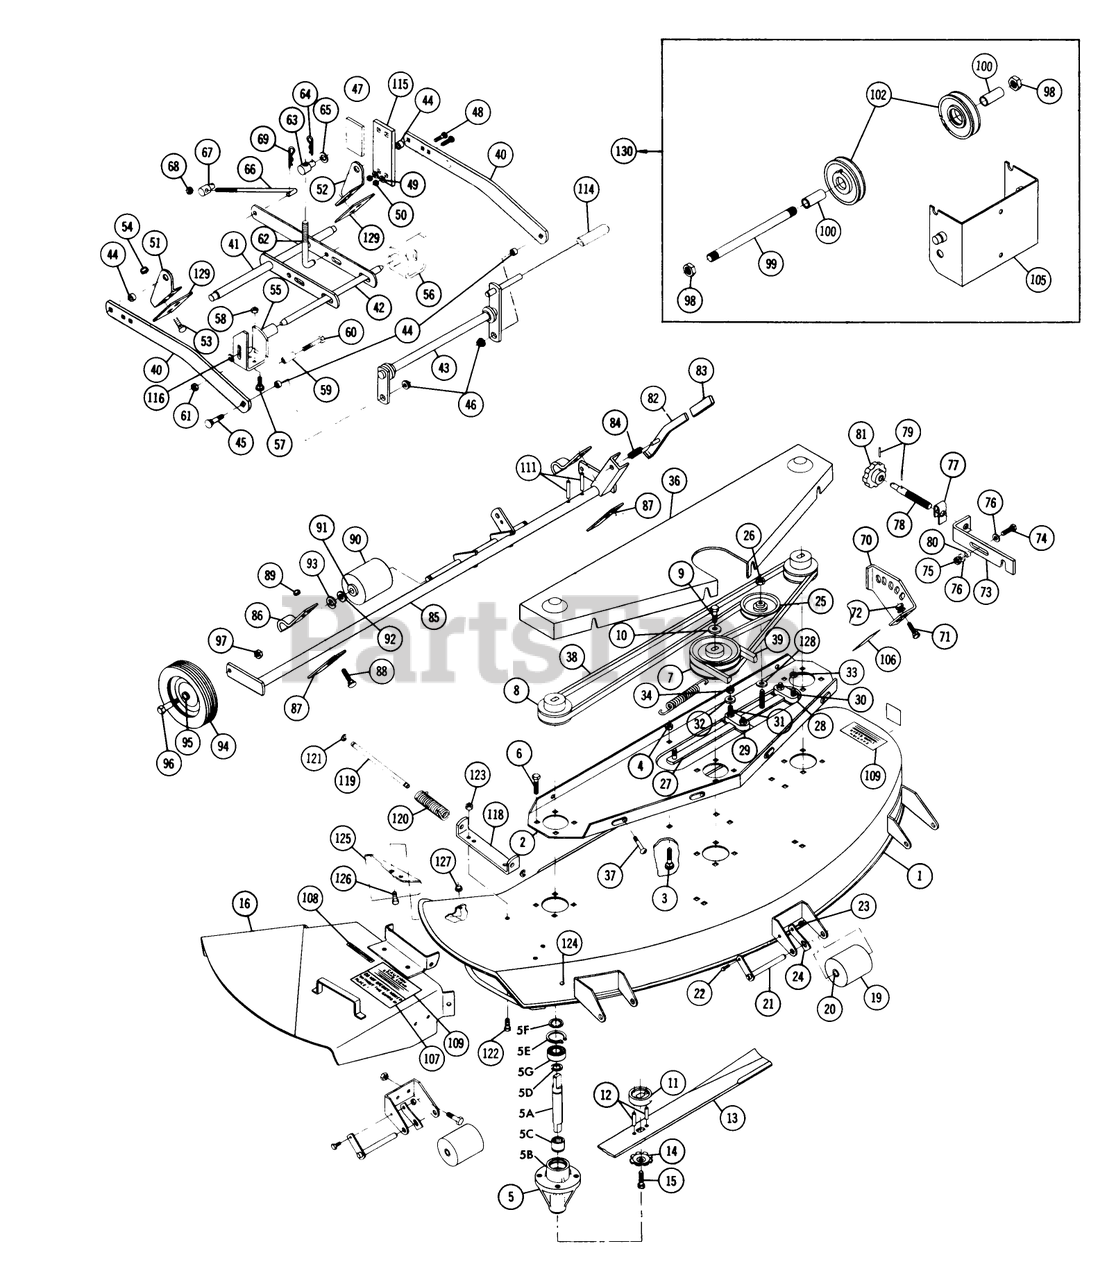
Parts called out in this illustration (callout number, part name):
1	Deck
2	Support
3	Bolt-Carriage
4	NUT
5	Spindle Assy.
5A	SHAFT SPINDLE
5B	HOUSING SPINDLE
5C	NEEDLE BEARING
5D	Snap Ring
5E	INT SNAP RING
5F	BUSHING
5G	BEARING
6	Bolt
7	Pulley-Center
8	Pulley-Right & Left
9	Bolt
10	WASHER
11	Cup-Spindle
12	SPIROL ROLL PIN
13	BLADE KIT 48 LF
14	WASHER
15	Bolt
16	Chute Extension
19	Roller
20	BUSHING
21	Roller Shaft
22	H H C S
23	Nut
24	SPRING ROLLER STOP
25	Pulley-Idler
26	Nut
27	ASSY BAR IDLER SUPPO
28	Side Block
29	SLIDE
30	Bolt-Carriage
31	Bolt-Carriage
32	WASHER 5/16 SAE
33	Nut
34	Nut
35	SPRING R
36	Cover
37	Screw
38	V-BELT
39	V BELT
40	Bar Draft
41	Leveler Ass-y.
42	SHAFT-FRONT R
43	Hitch Assy.
44	SPACER
45	Bolt
46	LOCKNUT-FLANGE
47	BUMPER
48	Bolt-Carriage
49	Collar
50	Nut
51	Bracket-R.H.
52	Bracket-L.H.
53	Bolt-Carriage
54	Nut
55	Bracket-RH Front
56	LH FT DECK BRKT A R
57	Bolt-Carriage
58	Nut
59	SPACER-BEARING
60	7/16-14X13/4 HEX BLT
61	Nut
62	LIFT ROD
63	ROD-TRUNNION LIFT
64	Hairpin
65	Washer
66	ROD-LEVELER
67	TRUNNION-LIFT
68	NUT
69	Hairpin Cotter
70	LH QUADRANT R
71	Bolt
72	NUT
73	Hitch Adjustment Link
74	Bolt
75	Nut
76	Washer
77	Detent Spring
78	HITCH ADJ SCREW
79	PIN-ROLL
80	SPACER
81	KNOB-ADJUSTMENT
82	Lever
84	SPRING-COMPRESSION
85	Gage Wheel Support
86	Machine Bolt
87	Bar
88	Bolt
89	NUT
90	Roller
91	BUSHING
92	Washer
93	E Ring
94	Wheel
96	BOLT-SHOULDER
97	Nut
98	Nut
99	SHAFT FRONT PULLEY
100	SPACER FRONT PULL R
101	SPACER-FRONT PULLEY
102	Pulley-V
105	Shield Assy.
106	Decal-Height Adj.
107	Decal-Caution
108	Decal-Edge of Cut
109	Caution Decal
110	DECAL-WHEEL HORSE
111	PIN-SPIROL
114	GRIP
115	PLATE-BUMPER R
116	WASHER
118	Deck Bracket
120	Spring
121	E-Ring, 3/8 Dia.
122	Bolt
123	Nut
124	Bumper Plug
125	Chute Guard
126	Bolt
127	Nut
128	Washer
129	PLATE
130	S.A. Front Idler-Complete
